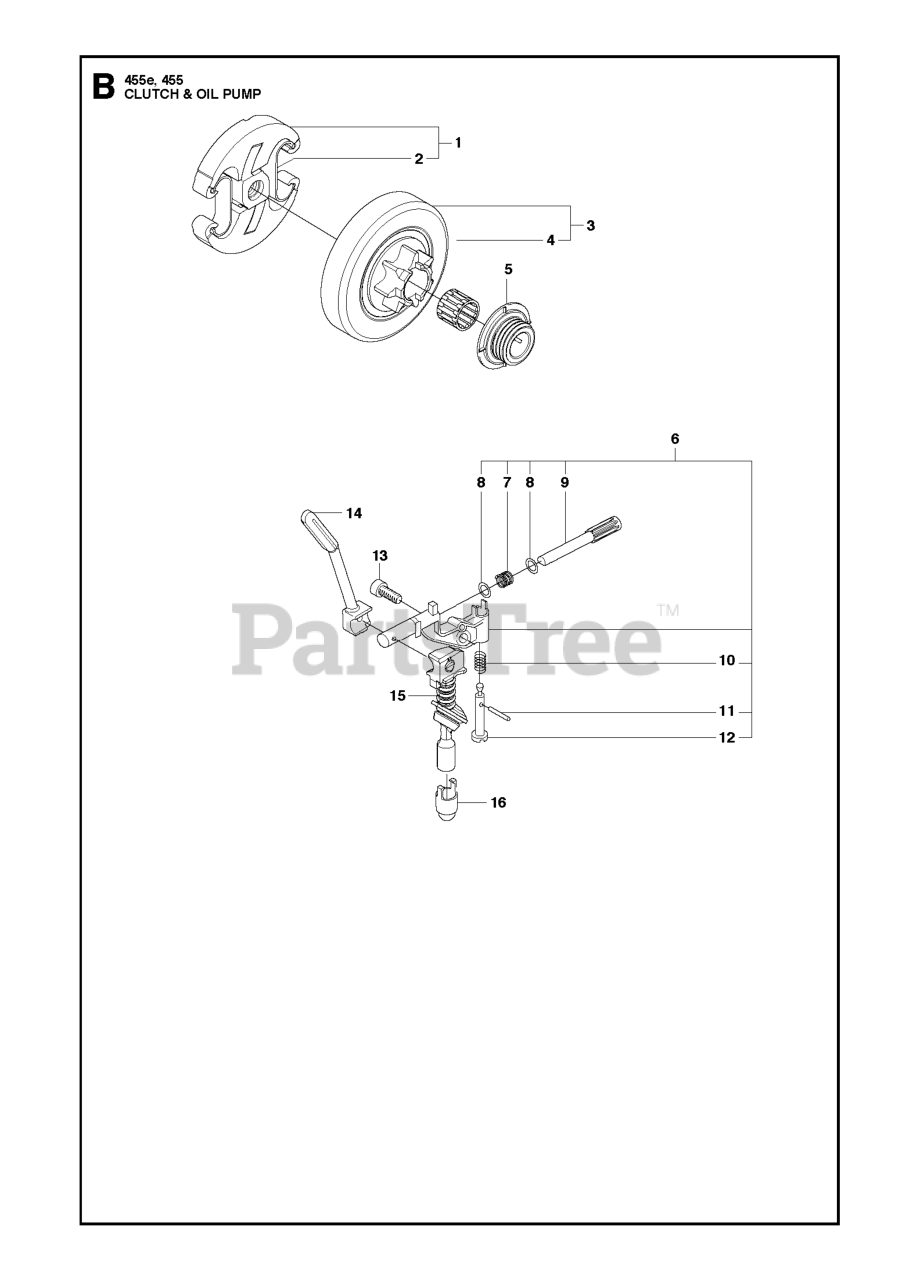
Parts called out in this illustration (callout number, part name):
3	CLUTCH DRUM
4	NEEDLE BEARING
5	GEAR WORM OILER
6	OIL PUMP ASSY
9	PUMP PISTON
16	OIL SCREEN
